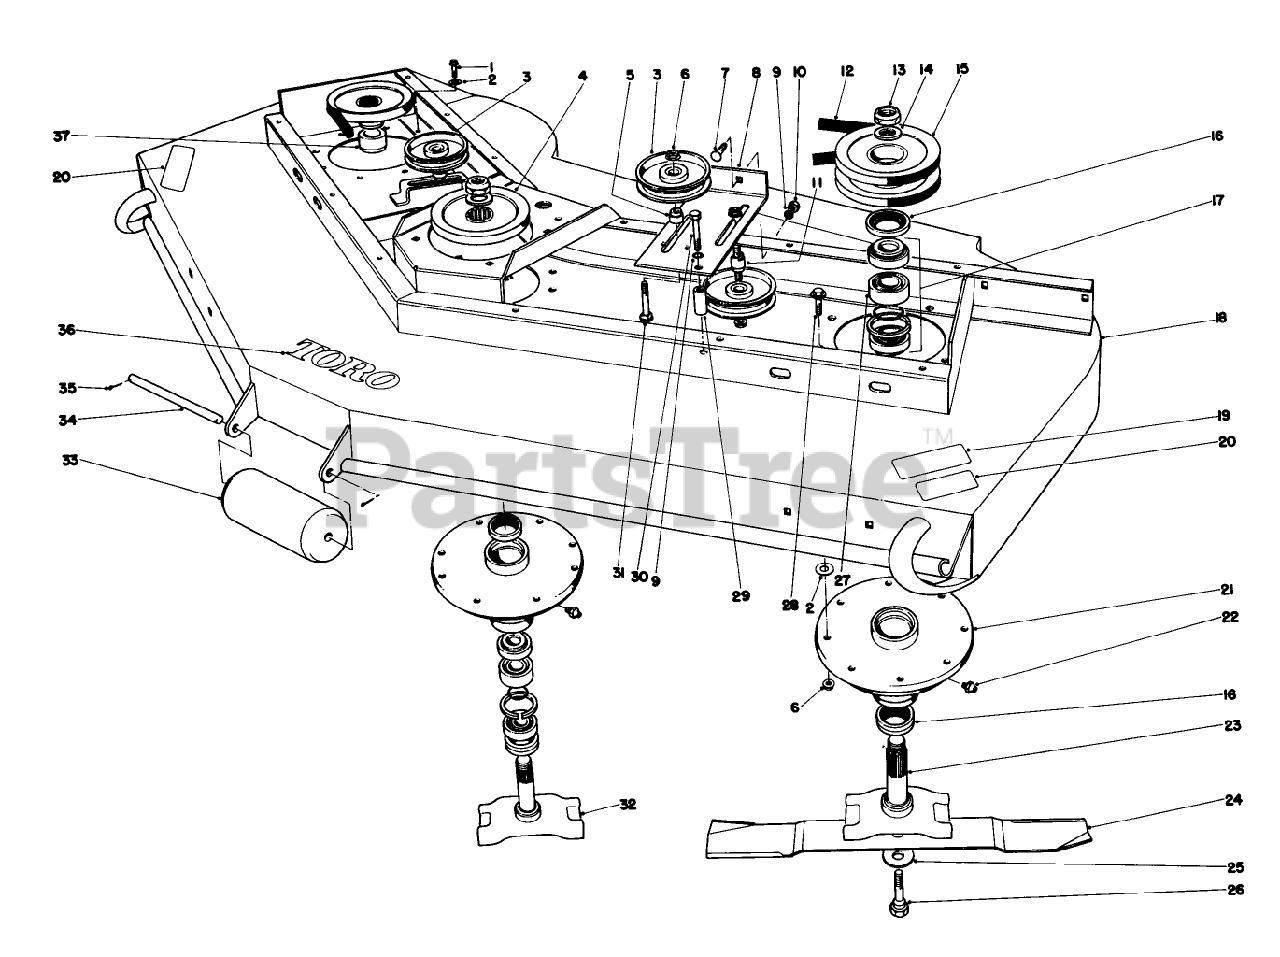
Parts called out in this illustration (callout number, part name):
1	SCREW-HHF
2	WASHER-FLAT
3	PULLEY-IDLER
4	PULLEY AND HUB ASM
5	SPACER-IDLER PULLEY
6	NUT-HF
7	SCREW-CARR
8	Idler Mount L.H.
9	WASHER-LOCK
10	NUT-HEX
11	STUD-IDLER
12	V-BELT
13	NUT-LOCK, NI
14	WASHER-THRUST
15	PULLEY-L.H. W.A.
16	SEAL-OIL
17	BEARING KIT (MATCHED SET)
18	Cutter Deck
19	Decal-Caution
20	DECAL-CAUTION, BLADE
21	Spindle Housing
22	FITTING-GREASE
23	OUTER SPINDLE WA
24	BLADE-STANDARD, LH, 25IN
25	WASHER-BELLEVILLE
26	CAPSCREW
27	Spacer Matched Set
28	SCREW-HHF
29	SPACER-IDLER MOUNT
30	SCREW-HH
31	SCREW-CARR
32	Spindle Ctr.
33	ROLLER-FRONT
34	ROLLER SHAFT
35	PIN-COTTER
36	TORO LOGO DECAL
37	Spacer R.H.Spindle
